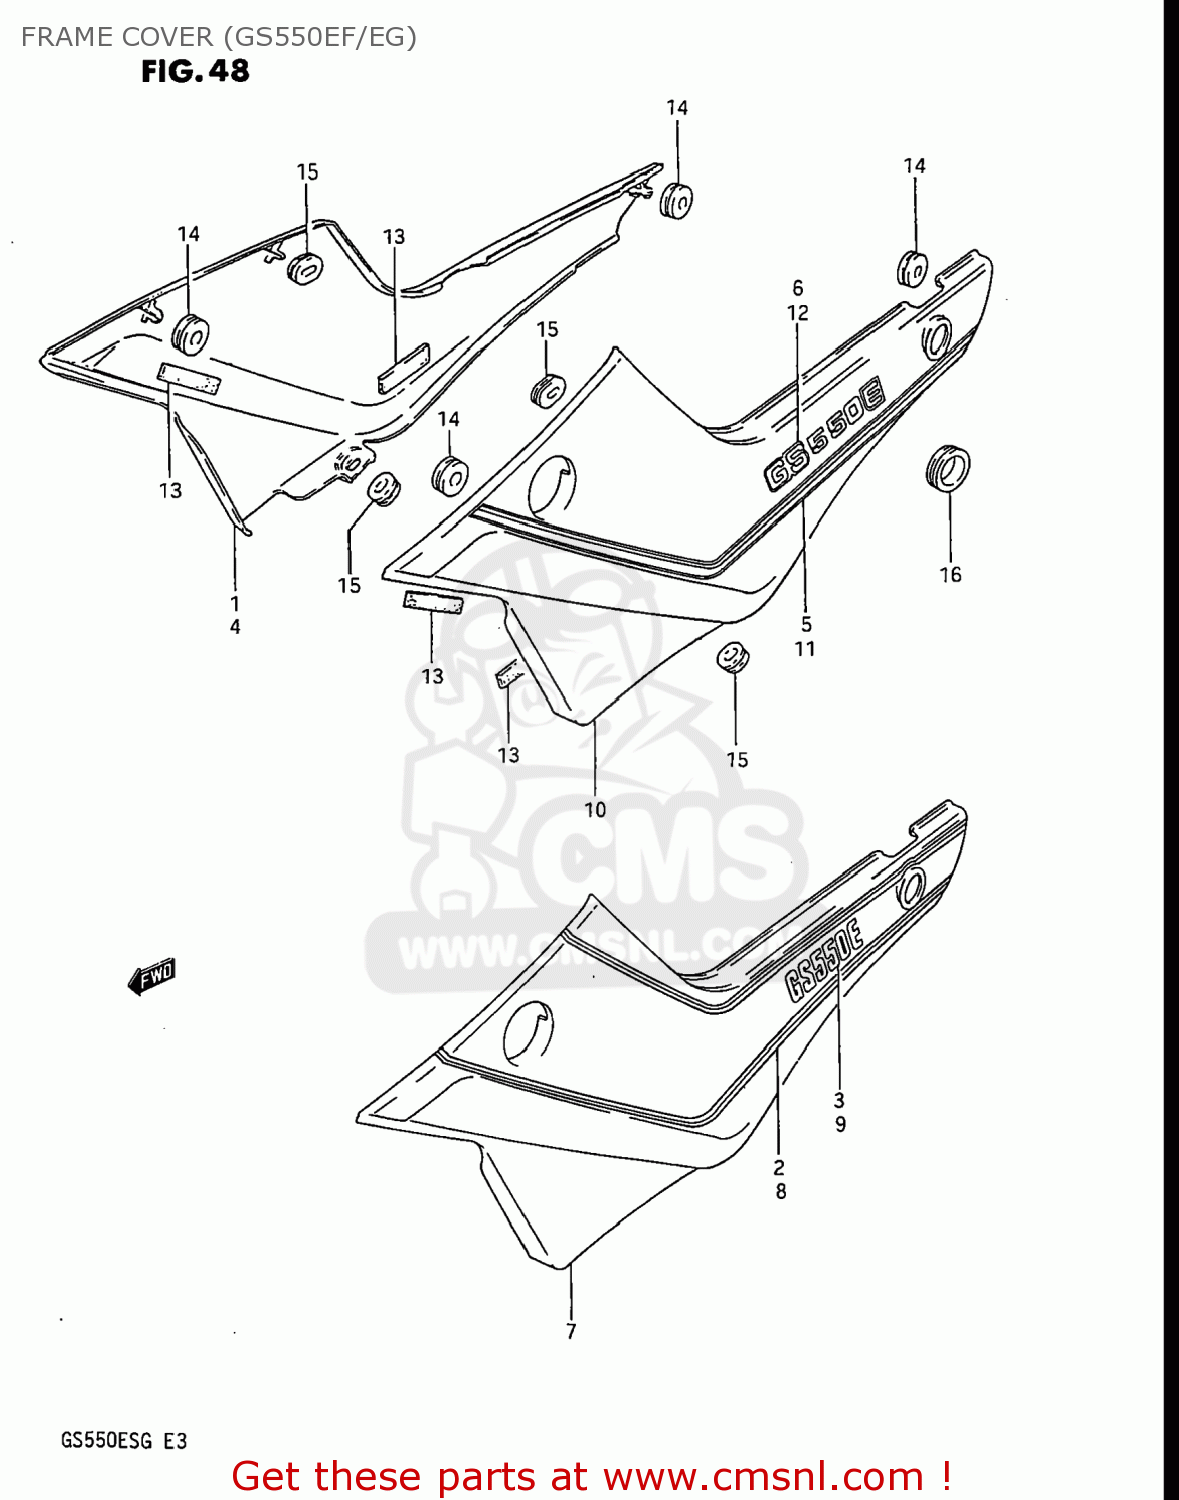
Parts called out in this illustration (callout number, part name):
1	COVER,FRAME,RIGHT
2	TAPE SET,FRAME COVER,RIGHT
3	EMBLEM
4	COVER,FRAME,RIGHT
5	TAPE SET,FRAME COVER RH
6	EMBLEM
7	COVER,FRAME,LEFT
8	TAPE SET,FRAME COVER
9	EMBLEM
10	COVER,FRAME,LEFT
11	TAPE SET,FRAME COVER,LEFT
12	EMBLEM
13	RUBBER,FRAME COVER
14	CUSHION
15	CUSHION
16	GROMMET,SEAT LOCK HOLE
